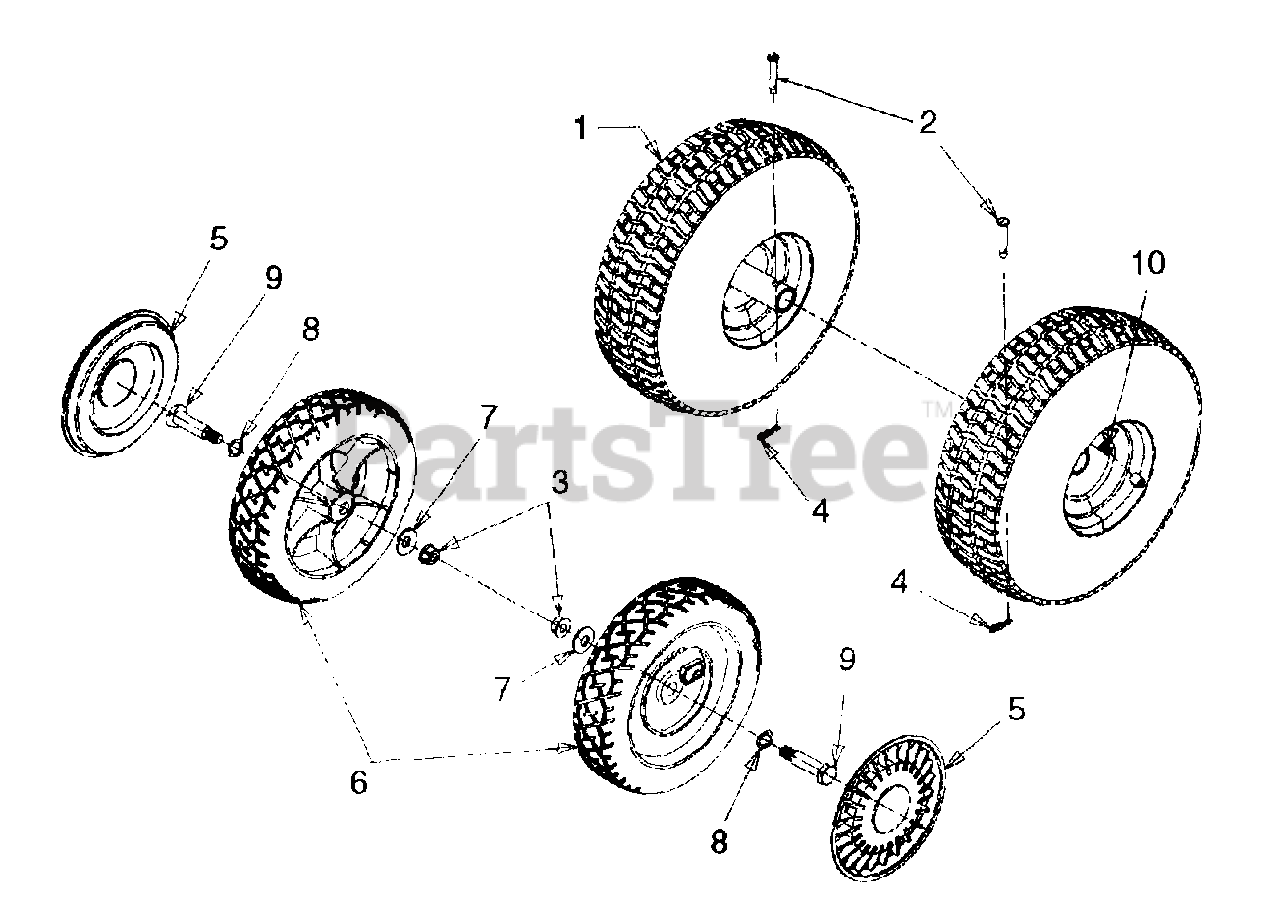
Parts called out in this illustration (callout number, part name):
1	Wheel Ass'y Complete
2	Pin, Clevis, .25 x 1.53
3	Nut, Hex Flange Lock, 3/8-16
4	Pin, Internal Cotter
5	Hubcap, Beige
6	Wheel Ass'y Complete, 8 x 2.0
7	Washer, Bell, .401 x .870 x .06
8	Washer, Wave, .53 x .78 x .013
9	Shoulder Bolt
10	Valve, Tubeless Air
